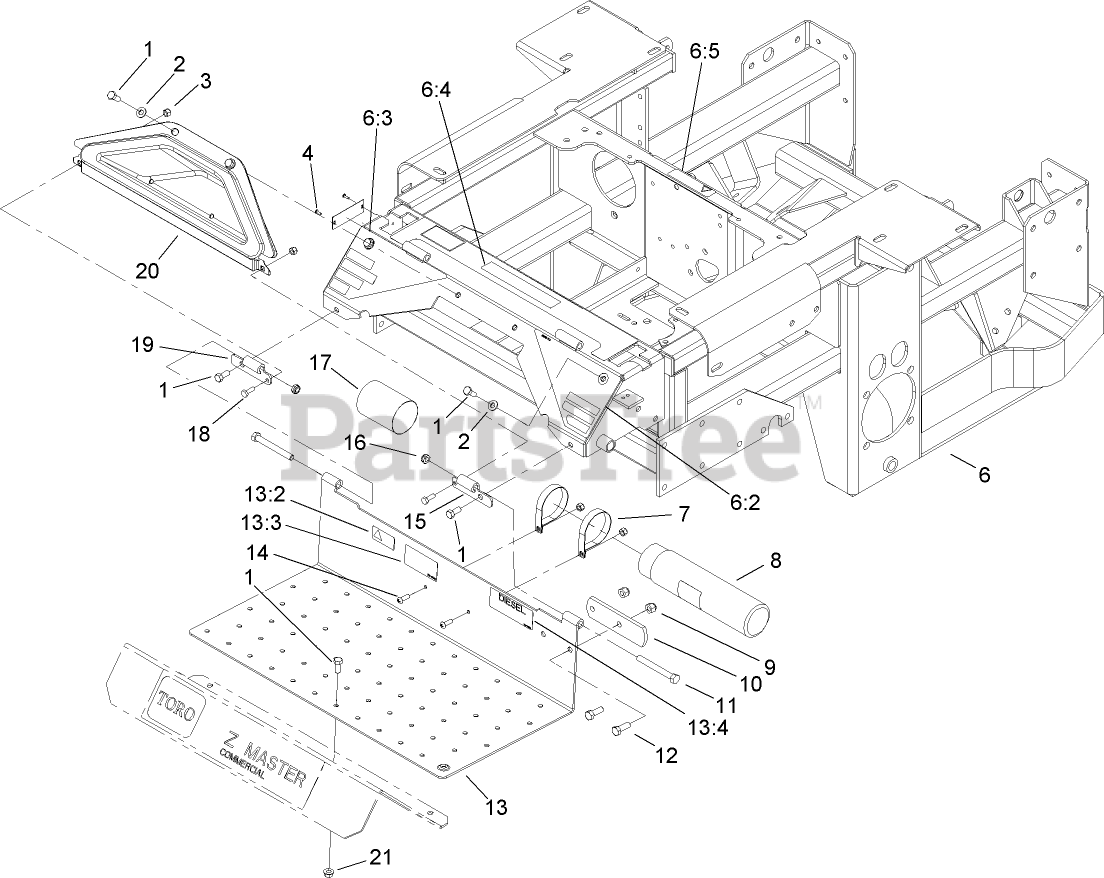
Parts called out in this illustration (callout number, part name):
1	SCREW-HH
2	WASHER-FLAT
3	NUT-LOCK, NI
4	RIVET
6	MAIN FRAME ASM
6:2	DECAL-DANGER, LEFT
6:3	DECAL-WARNING, RIGHT
6:4	DECAL-CONSOLE, TOP
6:5	DECAL-WARNING
7	R-Clamp
8	TUBE-MANUAL
9	NUT-LOCK, NI
10	STOP-BRAKE, PARK
11	SCREW-HH
12	SCREW-HH
13	FLOORPAN ASM
13:2	DECAL-PROTECTION, EAR
13:3	DECAL-LOCATION, MANUAL
13:4	DECAL-DIESEL
14	SCREW-PRH
15	Hinge-Floorpan, LH
16	NUT-LOCK, NI
17	CAP-HOUSING
18	SCREW-HH
19	Hinge-Floorpan, RH
20	Pocket
21	NUT-HF
